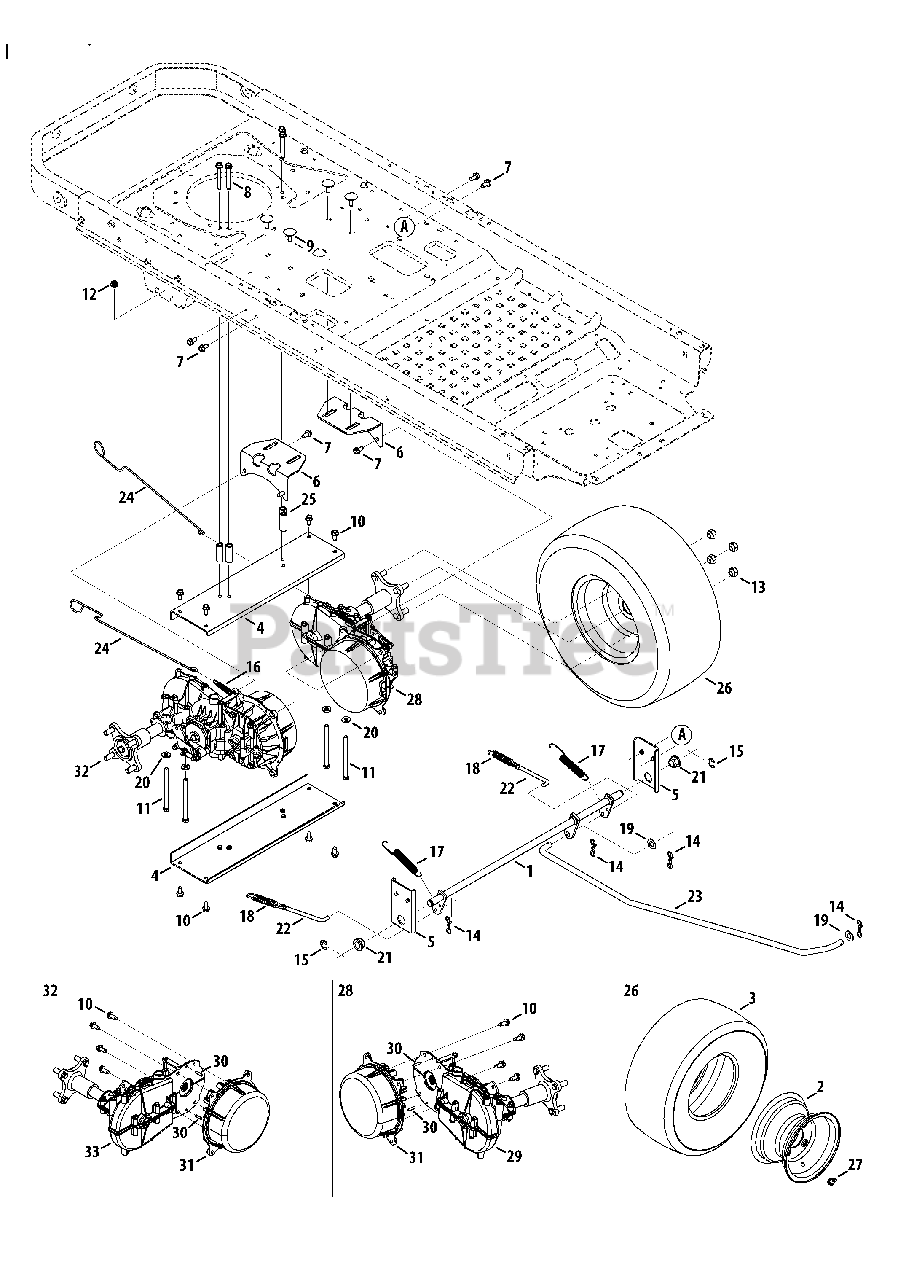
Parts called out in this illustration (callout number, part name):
1	Shift Assembly
3	Tire Only, 18 x 8.5-8
4	Axle Support Bracket
5	Shift Assembly Mounting Bracket
6	Transmission Mounting Bracket
7	Hex Washer Screw, 5/16-18 x .750
8	Hex Washer Screw, 5/16-18 x 2.50
9	Screw, 5/16-18 x 1.00
10	Hex Washer Head Screw, 5/16-18 x .75
11	Hex Cap Screw 5/16-18 x 4.50
12	Flange Lock Nut, 5/16-18
13	Lug Nut, 7/16-14
14	Bow-Tie Cotter Pin
15	E-Ring, .625
16	Extension Spring, .429OD x 2.515
17	Extension Spring, .63 DIA x 4.95 LG
18	Extension Spring, .59 OD x 4.00 LG
19	Flat Washer, .510 x 1.00 x .060
20	Flat Washer, .344 x .750 x .120
21	Hex Flange Bearing
25	Spacer, .345 x .625 x 1.798
26	Complete Wheel, 18 x 8.5-8
27	Valve Tubeless
28	Transmission Assembly, Whl Mtr, RH
29	Tranmission Assembly, RH
30	Dowel Pin, 3/16 x 3/4
31	Electric Motor, 48V
32	Transmission Assembly, Whl Mtr, LH
33	Tranmission Assembly, LH
